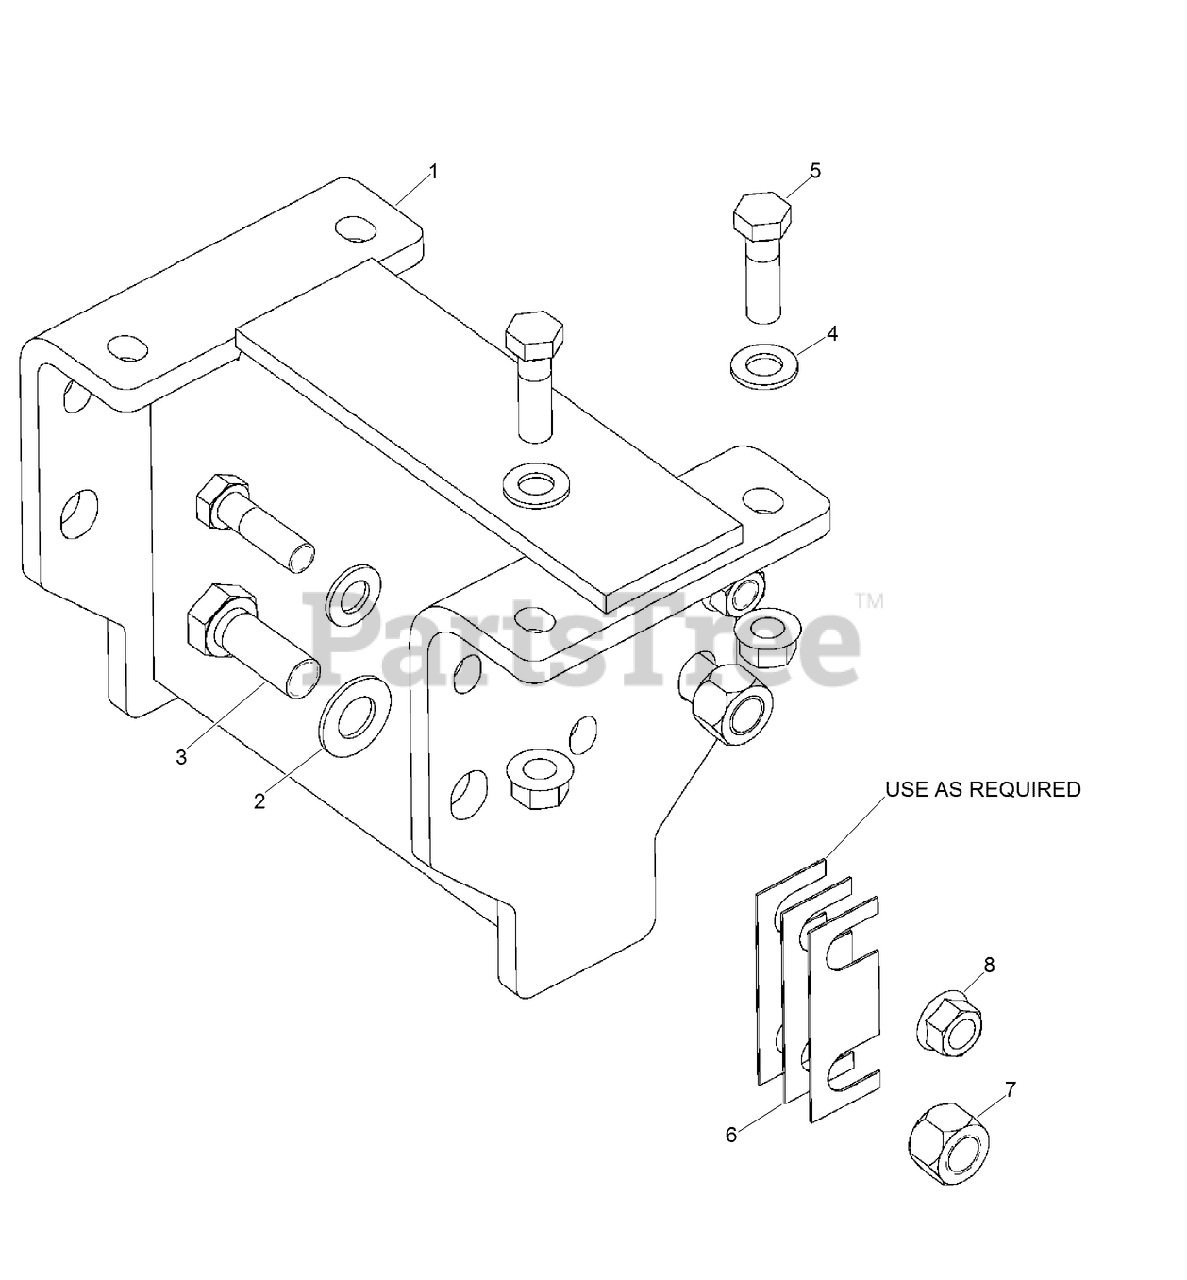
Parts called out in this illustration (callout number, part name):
1	EXTENSION - Rock Boom
2	WASHER-FLAT
8	NUT-HEX FLANGE
